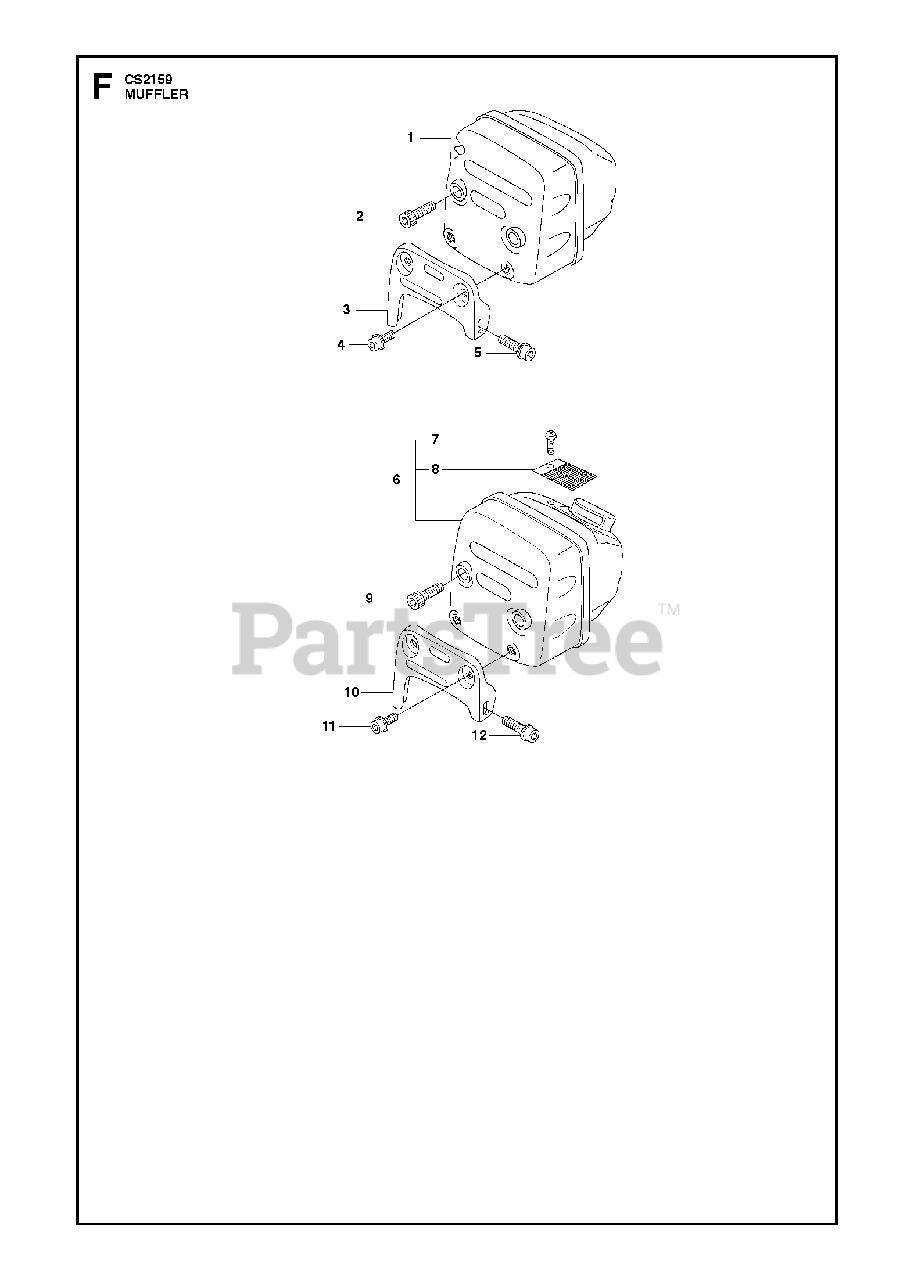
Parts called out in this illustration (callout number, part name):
1	MUFFLER ASSY
2	SCREW MC6S 6X16
4	SCREW M5 X 10
6	MUFFLER CAT
7	SCREW
8	SPARK ARRESTOR SCREEN
9	SCREW MC6S 6X16
11	SCREW M5 X 10
